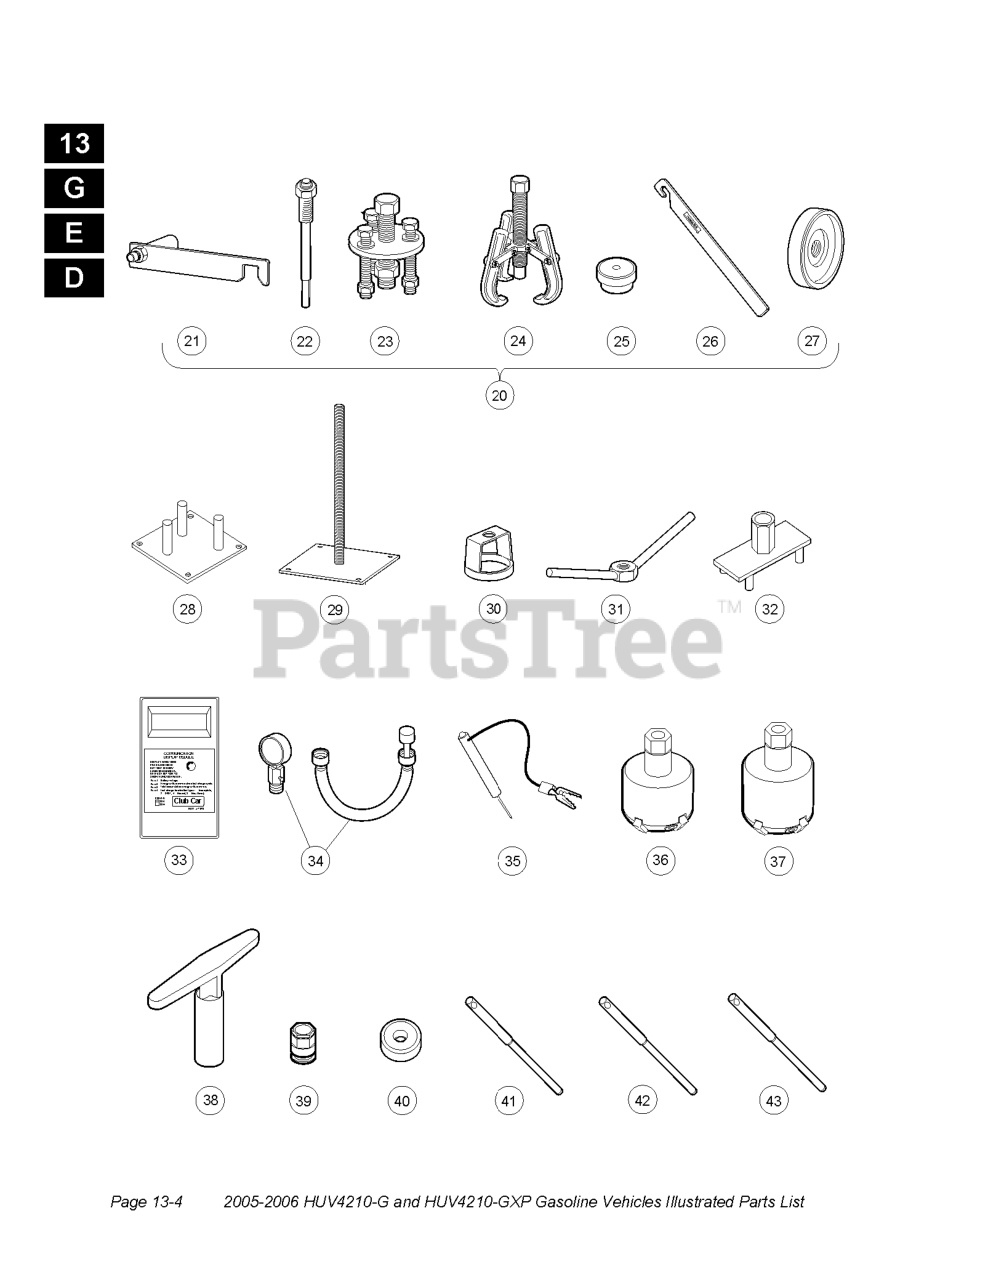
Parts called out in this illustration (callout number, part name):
20	C.C. CLUTCH TOOL KIT
21	TOOL, CLUTCH ALIGNMENT
22	TOOL, CLUTCH PULLER
23	CLUTCH DRIVE HUB PULLER
24	DRIVEN CLUTCH CAM PULLER
25	DRIVEN CLUTCH PULLER PLUG
26	DRIVE CLUTCH HOLDER TOOL ASM.
27	PRESS WELDMENT
29	TOOL-SPRING COMPRESSION BASE
30	TOOL-SPRING COMPRESSION COLAR
31	TOOL-SPRING COMPRESSION COLAR
32	TOOL-SPIDER PRIMARY
34	COMPRESSION GUAGE AND ADAPTER
35	CONTINUITY TESTER
36	CUTTER, VALVE SEAT, #122
37	CUTTER, VALVE SEAT, #115
38	ADAPTER, T-WRENCH
39	ADAPTER, T-WRENCH
40	Cutter, Valve Seat, 60 Degree (requires item 59)
41	PILOT, 6.6 MM
42	PILOT, 6.62 MM
43	PILOT, 6.65 MM
